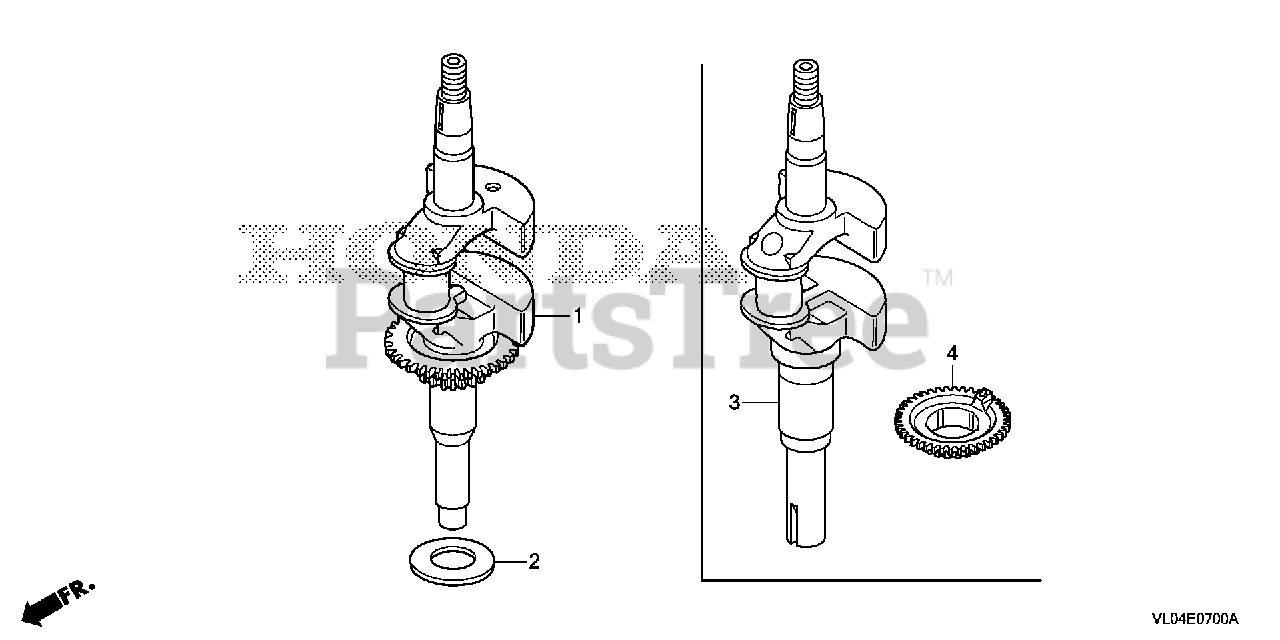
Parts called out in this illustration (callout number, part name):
2	WASHER, THRUST
3	CRANKSHAFT
4	PULLEY, TIMING BELT DRIVE
